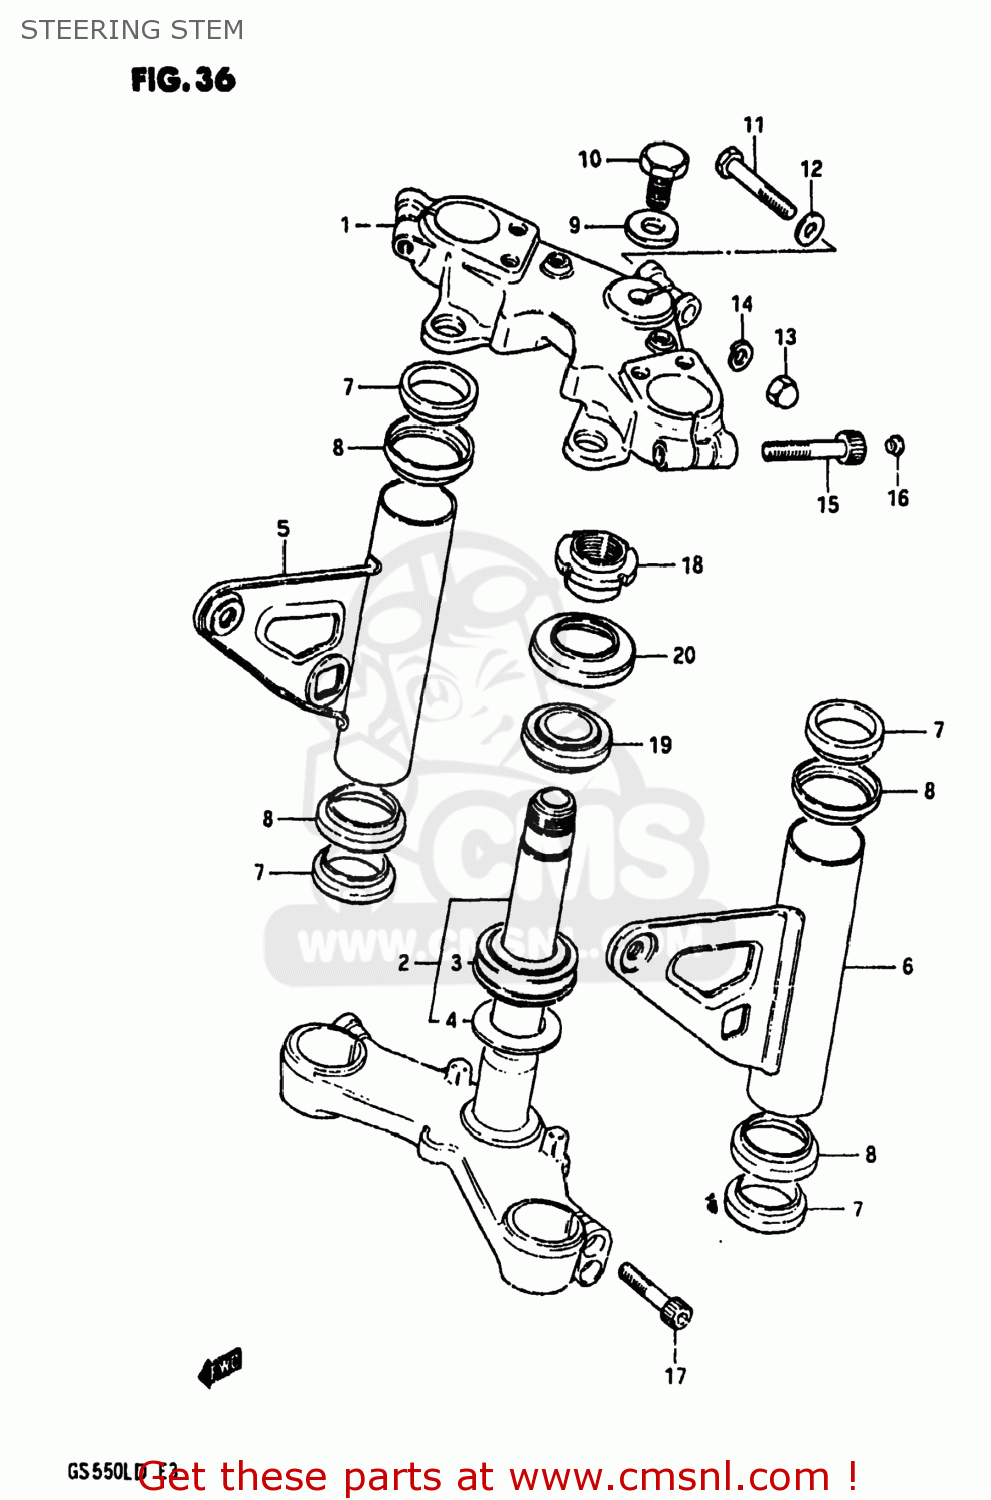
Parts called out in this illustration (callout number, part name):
1	HEAD,STEERING STEM
2	STEM,STEERING
3	BEARING
4	WASHER,THRUST
5	BRACKET,HEADLAMP,RIGHT
6	BRACKET,HEADLAMP,LEFT
7	CUSHION
8	CAP,HEADLAMP BRACKET
9	WASHER
10	BOLT,STEERING STEM HEAD
11	BOLT
12	WASHER
13	NUT,M8X1.25X12
14	LOCK WASHER
15	NUT,STEM HEAD
16	CAP(OD:20)
17	BOLT
18	NUT,STEERING STEM
19	TAPER,ROLLER BEARING
20	DUST SEAL,STEERING UPR
